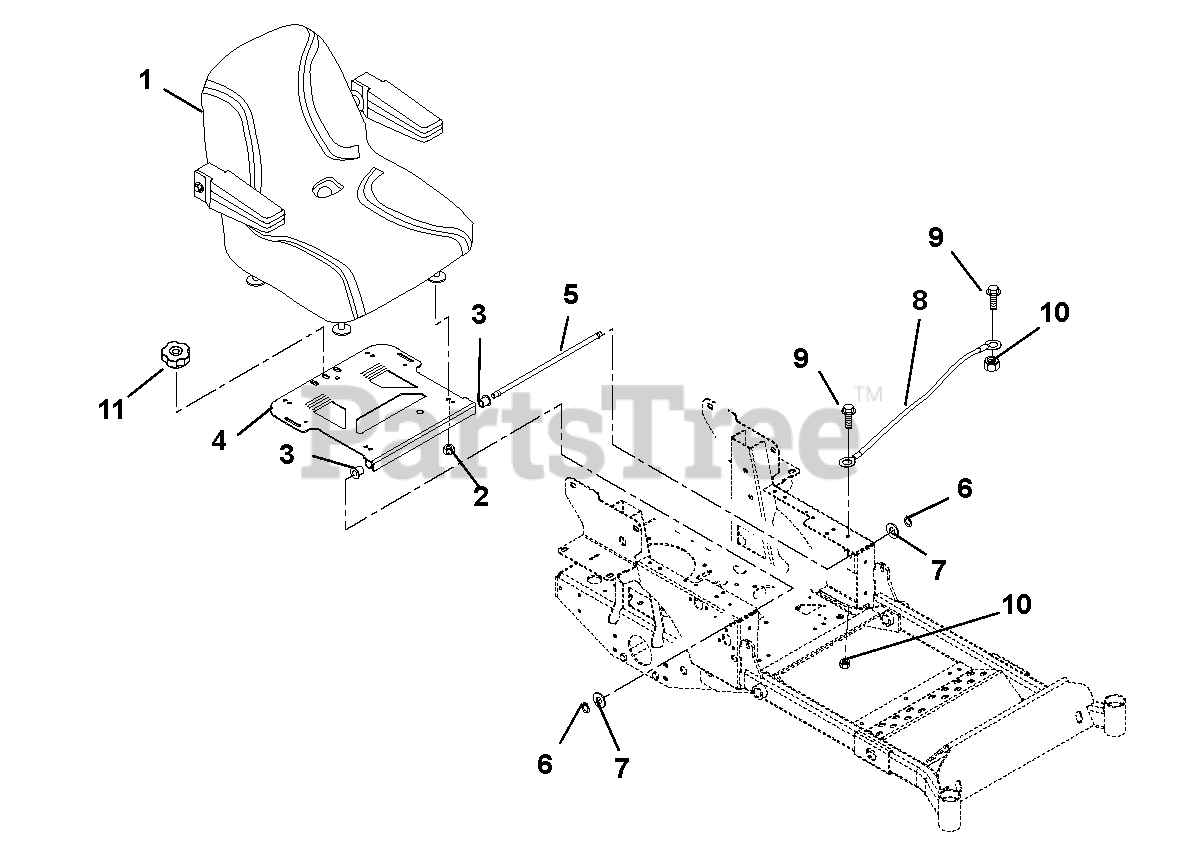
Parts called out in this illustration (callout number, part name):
2	Nut, Nyloc Flange .3125-18
3	Bushing, Flange .515 x .750 x .745 x 1.00
4	Seat Pivot Mount
5	Rod, Seat Frame Pivot
6	Ring, Retaining External .50 x .05
7	Washer, Flat Steel .531 x 1.00 x .063
8	Cable, Hood
9	Bolt, Hex .25-20 x .75 Grade 5
10	Nut, Nyloc Flange .25-20
11	Knob, Clamping .312-18
